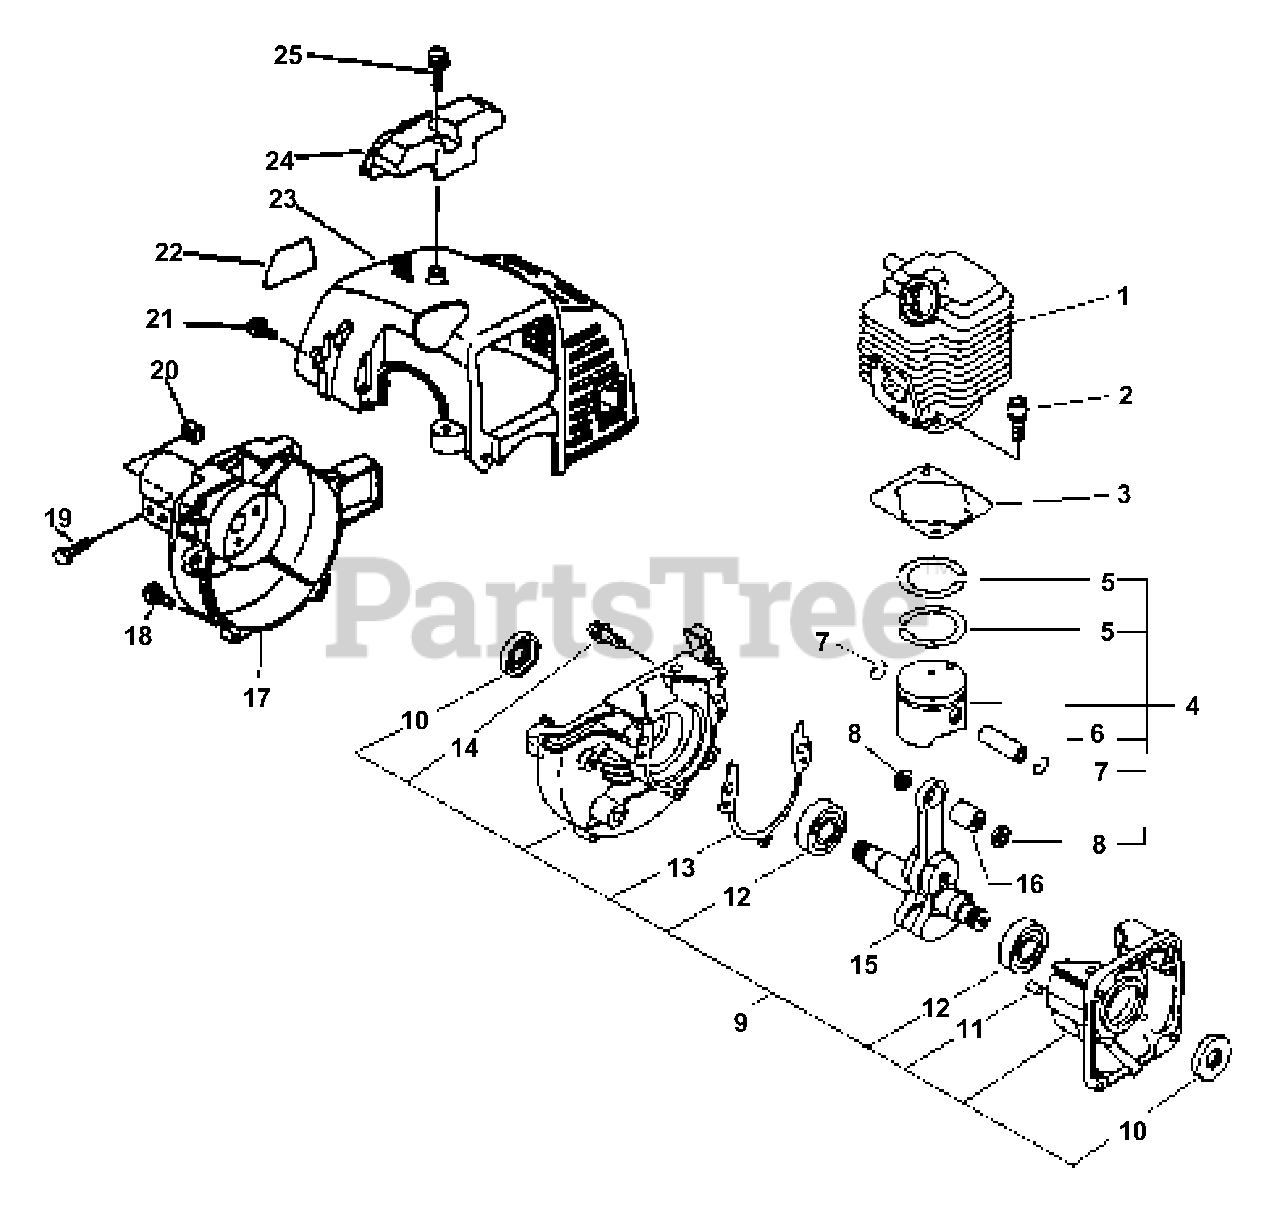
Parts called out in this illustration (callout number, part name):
1	CYLINDER
2	SCREW - 5X22
3	GASKET, CYLINDER
4	PISTON KIT
5	RING, PISTON
6	PIN, PISTON
7	RING, RETAINING
8	SPACER, PISTON
9	CRANKCASE KIT
10	SEAL, OIL
11	PIN - LOCATING
12	BEARING, BALL - 6201
13	GASKET, CRANKCASE
14	SCREW - 5X28
15	CRANKSHAFT ASSY
16	BEARING, NEEDLE
17	FAN CASE ASSY
18	SCREW - 5X14
19	BOLT - 5X28
20	NUT - 5 -- SQUARE
21	SCREW - 4X12 -- TAPPING
22	LABEL - MODEL PE-2000
23	COVER, ENGINE - GRAY
24	GUARD, TOP - GRAY
25	SCREW - 5X16 -- TAPPING
